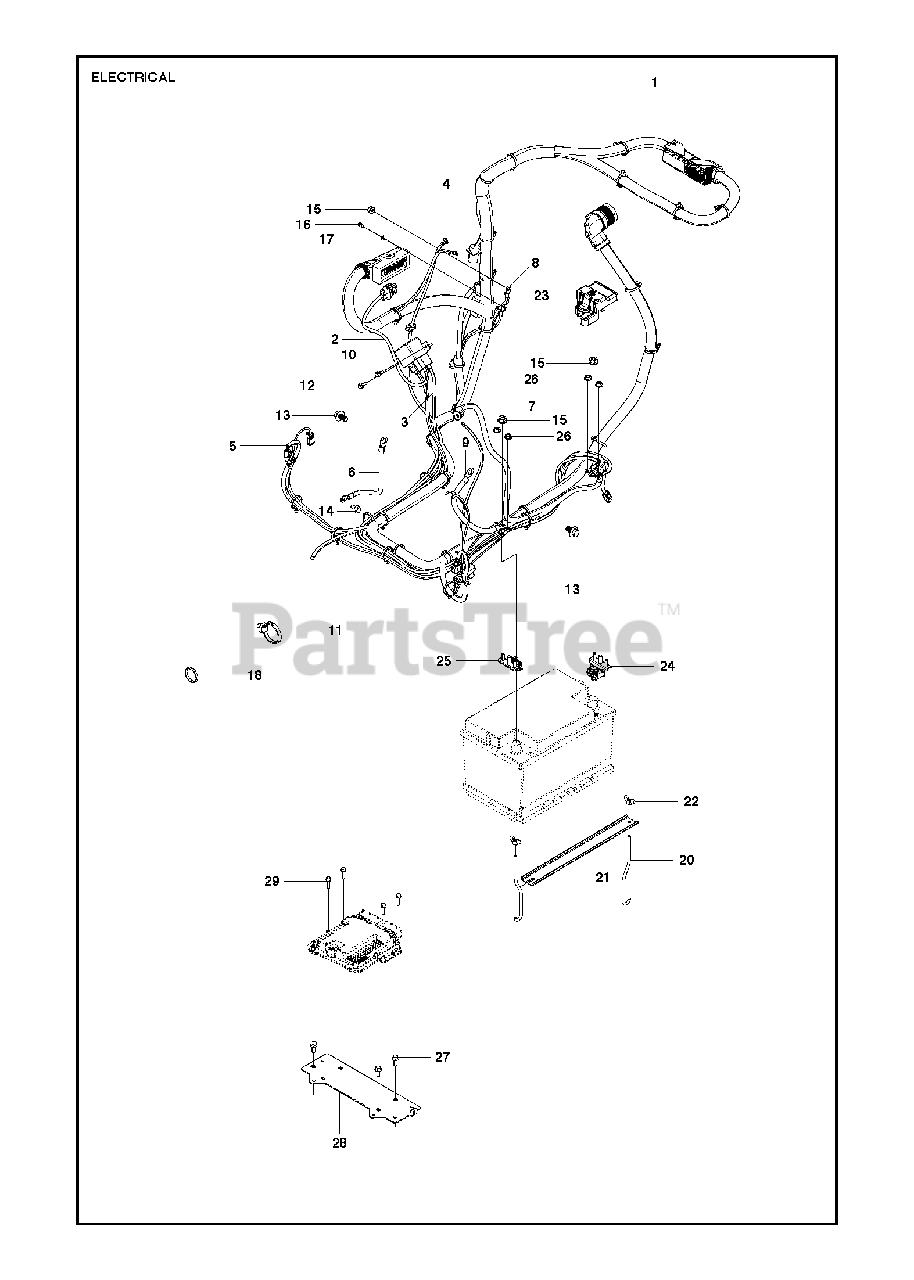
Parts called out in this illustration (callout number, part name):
2	HARNESS ASSYHeat Plug Relay
3	HARNESS ASSYBATT+ Heat Plug
4	HARNESS ASSYBATT+ Generator
5	HARNESS ASSYBATT+ Hydraulic Pump
6	HARNESS ASSYGROUND- Hydraulic Pump
7	HARNESS ASSYBATT+ Starter
8	HARNESS ASSYBATT+ Relay Box
9	HARNESS ASSYBATT- Chassie
15	HEXAGON NUT FLANGE
16	SCREW EHHM
17	WASHER
26	HEXAGON NUT FLANGE
